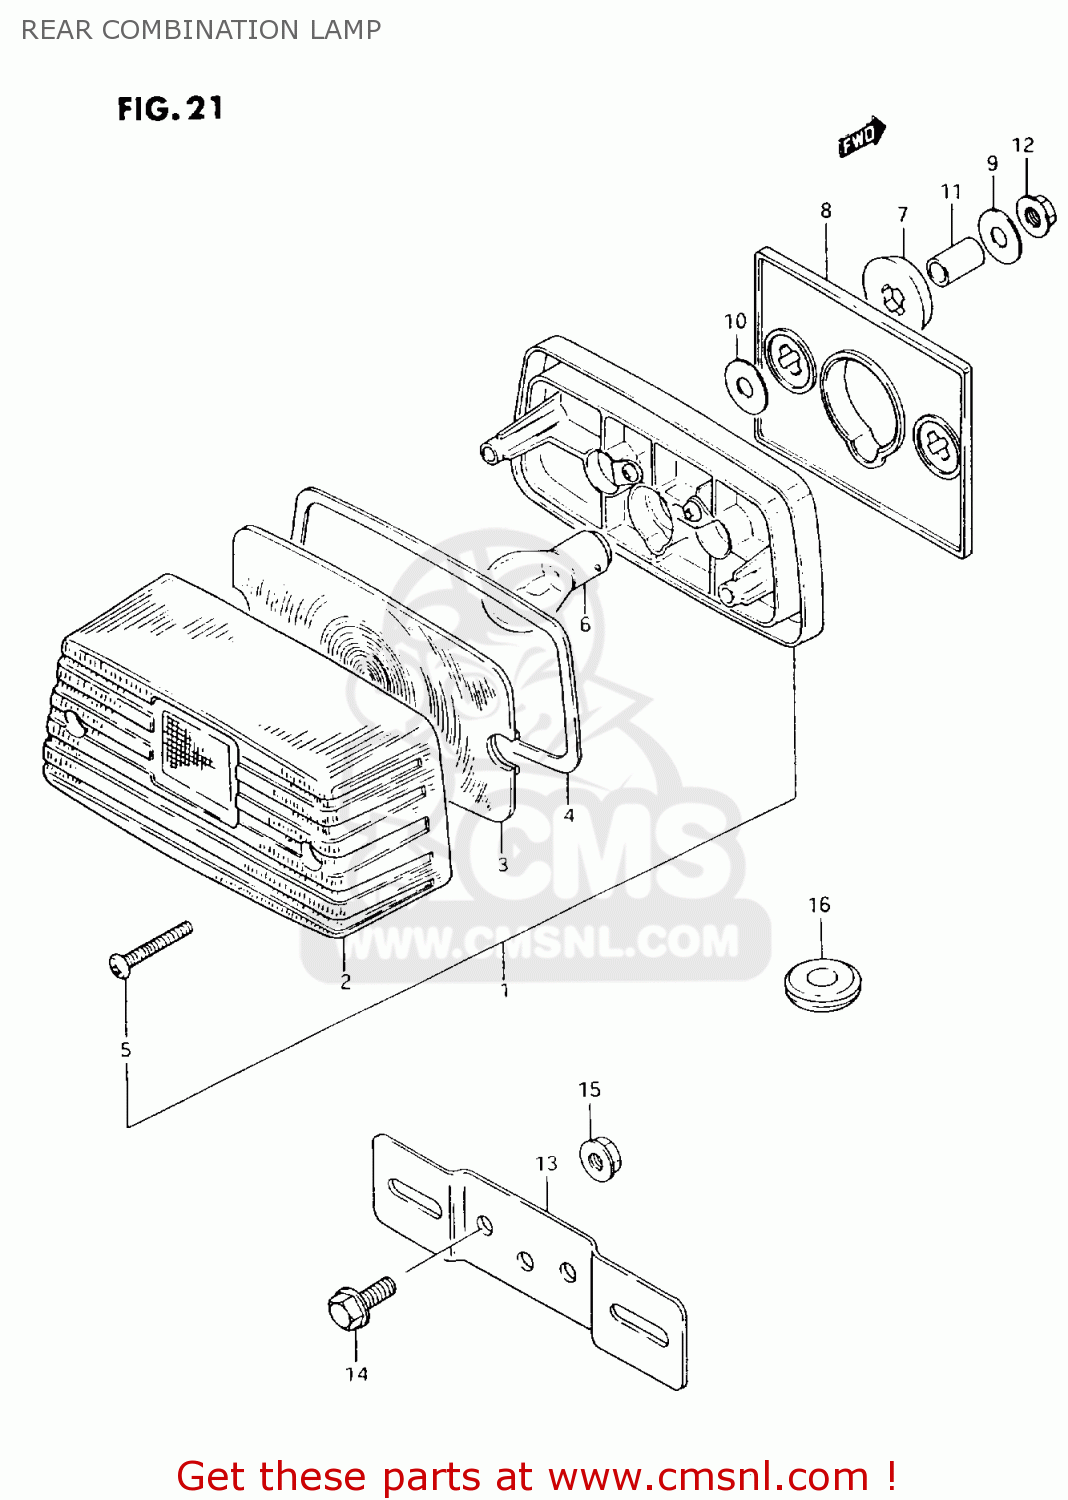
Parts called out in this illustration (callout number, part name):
1	LAMP ASSY,RR COMBINATION
2	LENS
3	UNDER LENS
4	GASKET (NAS)
5	SCREW
6	BULB(6V10/3W,STANLEY,A4854H)
7	CUSHION,RR COMBINATION LAMP
8	CUSHION,RR COMB LAMP NO.1
9	WASHER(5.5X20X1.2)
10	WASHER(5.2X16X1)
11	SPACER(6.5X9X9)
12	NUT
13	BRACKET,PLATE LICENSE
14	BOLT
15	NUT
16	GROMMET
